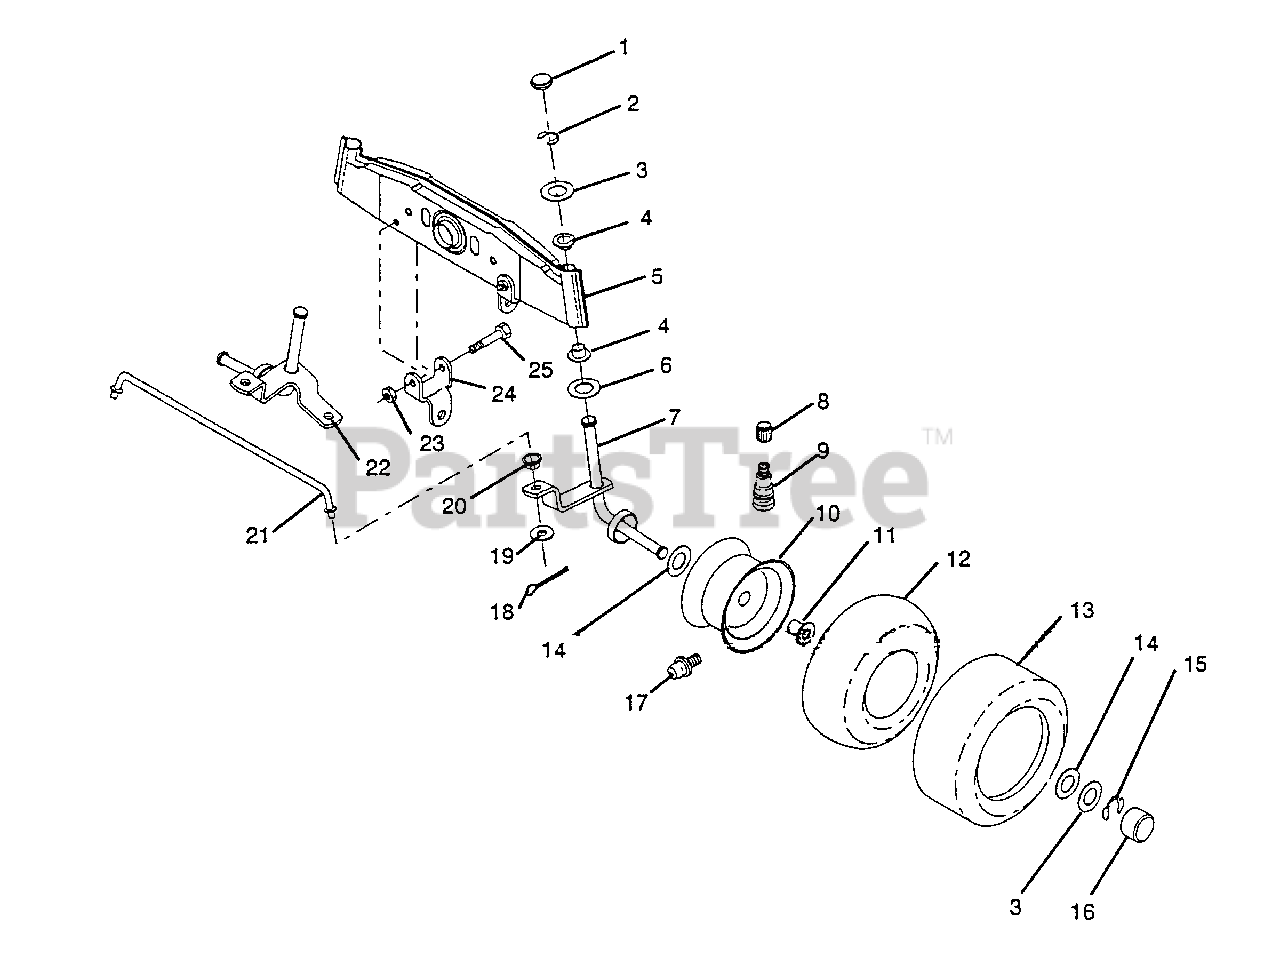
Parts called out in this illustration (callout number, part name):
1	Cap, Spindle
2	Ring, Clip
3	Washer 25/32 x 1-5/8 x 16 Ga.
5	Axle, Front
6	Bearing, Thrust
7	Spindle R.H. Asm.
8	Cap, Valve
9	Stem, Valve
10	Rim
11	Bearing, Flange
13	Tire, Front
14	Washer 25/32 x 1-1/4 x 16 Ga.
15	Ring, Clip
17	Fitting, Grease
18	Pin, Cotter 1/8 x 3/4
19	Washer 13/32 x 13/16 x 16 Ga.
22	Spindle, LH. Asm.
23	Nut, Crownlock 5/16-18
24	Bracket, Front Stabilizer Link
25	Bolt, Hex, Fin. 5/16 x 18 UNC x 2-1/2
